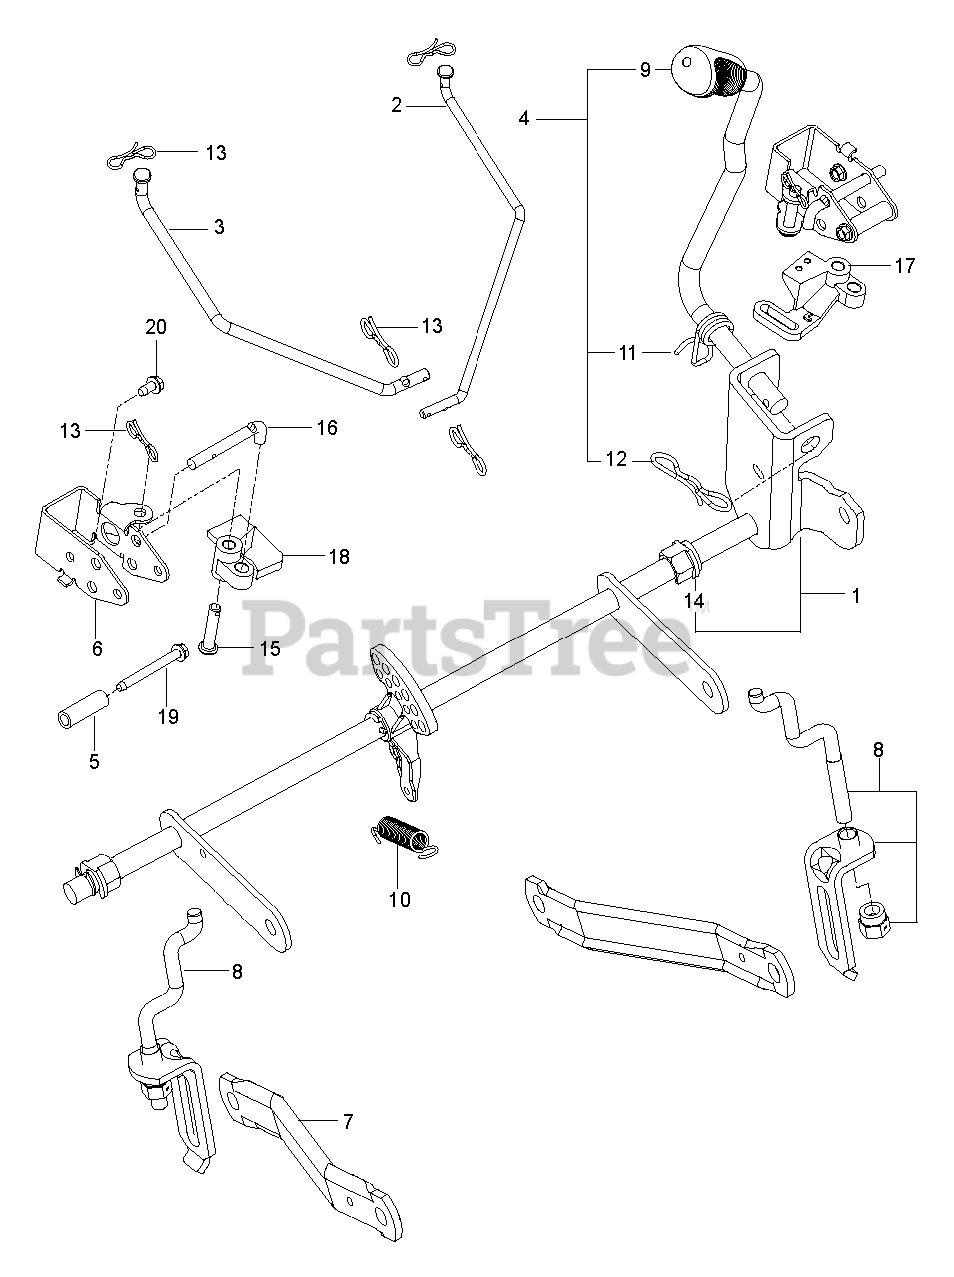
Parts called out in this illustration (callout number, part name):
1	SHAFT.ASM.RZ.DECK.LIFT.SRV
2	LINK.BRAKE.PARK.UPPER.LH
3	LINK.BRAKE.PARK.UPPER.RH
4	LIFT.LEVER.ASM.RZ.SERVICE
5	SPACER.334.ID.5.OD.1.5.L
6	BELLCRANK.BRACKET
7	ARM.SUSPENSION.MOWER
8	LINK.ASM.RZ.LIFT.SERVICE
9	GRIP.HANDLE.LIFT.PVC.428
10	RETURN.BRAKE.PARK.AUTO
11	SPRING.TORSION.LIFT.HANDLE
12	PIN.COTTER.7/16.BOW TI.
13	PIN COTTER;LOCKING;BOWTIE;1IN
14	PLASTIC NUT
15	PIN.5.16X1.5
16	ROD.PUSH.BRAKE
17	BELLCRANK.LH
18	BELLCRANK.RH
19	SCREW THD;ROLL;1/4-20 X 2.25
20	SCREW.1/4-20X5/8
